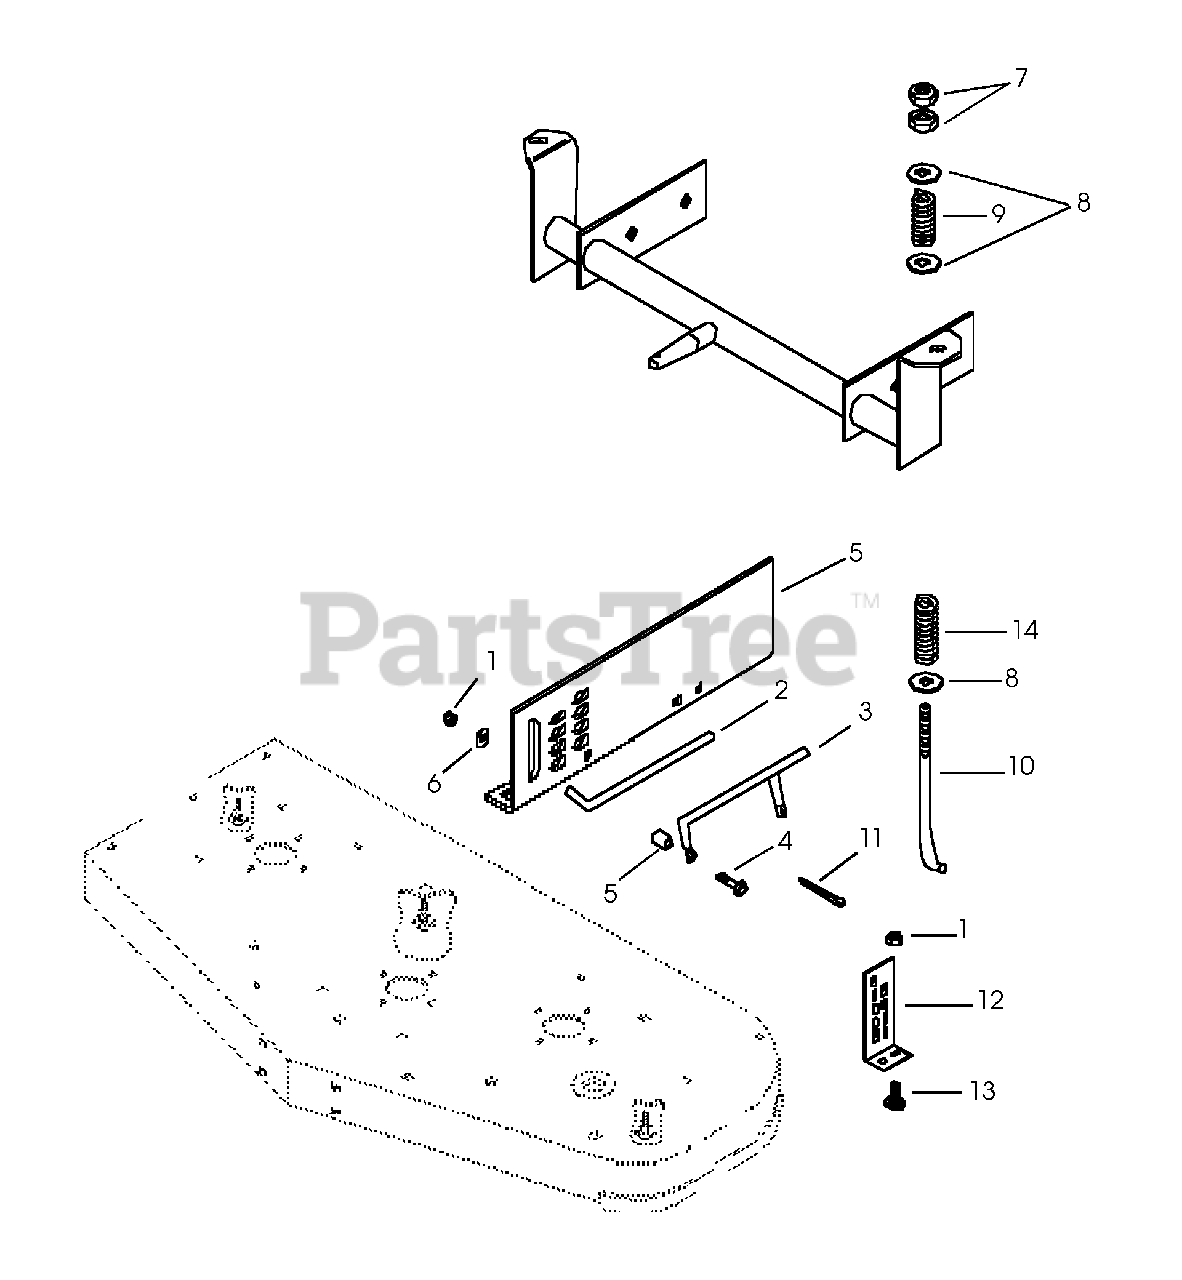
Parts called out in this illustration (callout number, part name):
1	Nut-Locking-Center .38-16
2	Pin-Mower Locking
3	Handle
4	Bolt-Hex .38-16 x 1.50 Grade 5
6	Washer-Flat-Steel .406 x .812 x .065
7	Nut-Hex .50-13
8	Washer-Flat-Steel .505 x .880 x .072
9	Spring-Compression .125 x .78 x 1.00
10	Rod-Height Adjustment
11	Pin-Klik 1.000 x .188 x 1.25
12	Bracket Rear Adjustment-Right Hand
12	Bracket Rear Adjustment-Left Hand
13	Bolt-Round Head Square Neck .38-16 x .75
14	Spring-Compression .095 x .75 x 6.25
